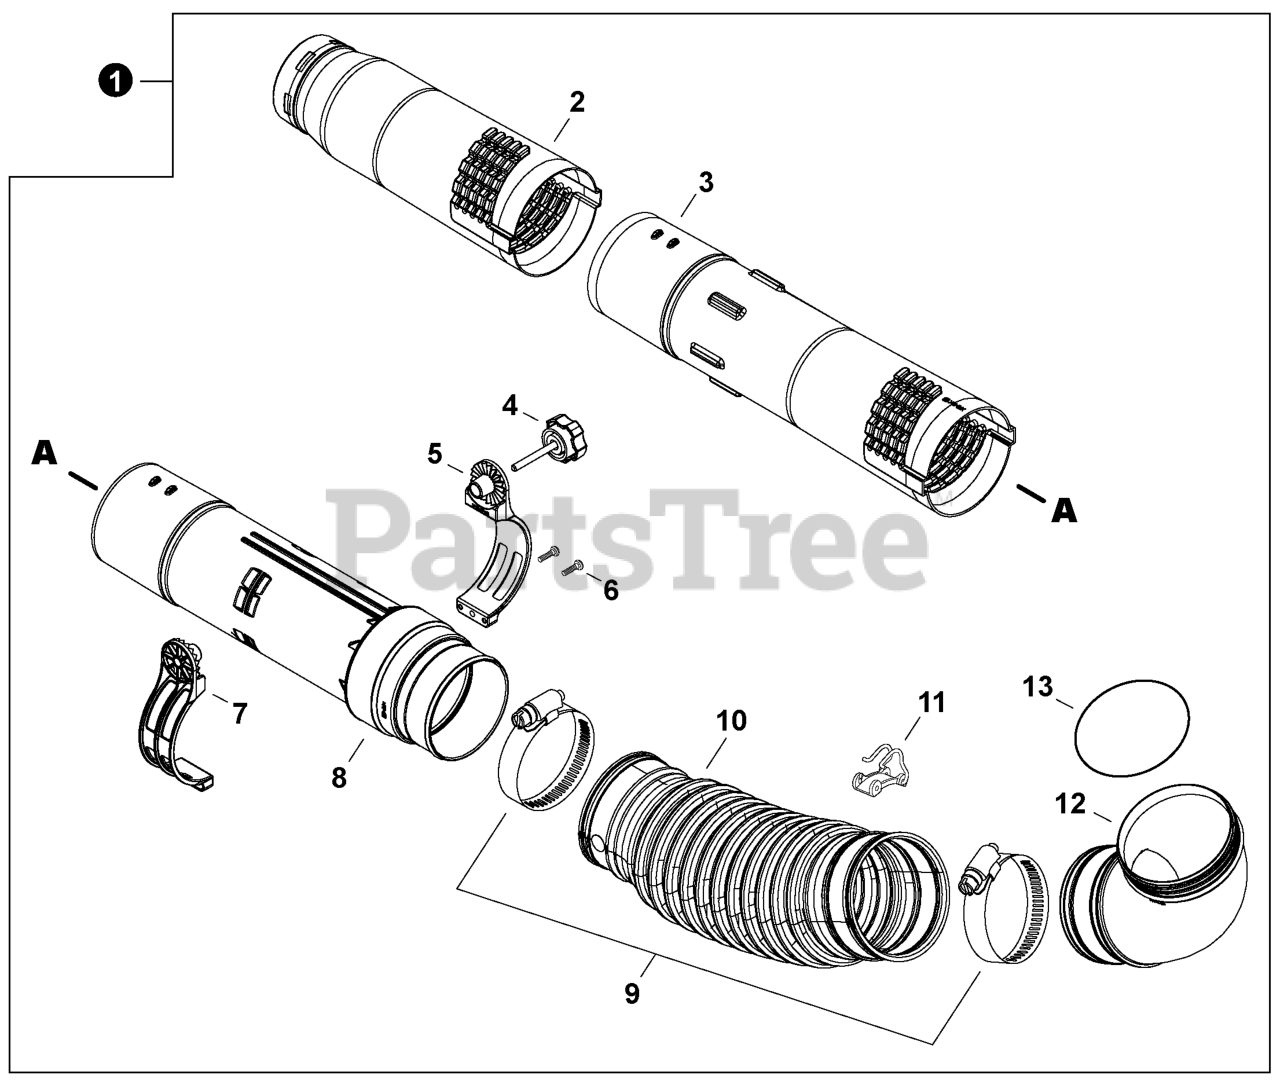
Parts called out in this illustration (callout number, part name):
1	TUBE KIT, BLOWER, TUBE MOUNT
2	TUBE, BLOWER - NOZZLE
3	TUBE, BLOWER - STRAIGHT
4	KNOB, SCREW
5	BRACKET, HANDLE - RIGHT
6	BOLT, TORX 5x20
7	BRACKET, HANDLE - LEFT
8	TUBE, BLOWER - SWIVEL
9	TUBE, BLOWER - FLEXIBLE
10	CLAMP - BAND
11	CLIP, CABLE
12	TUBE, BLOWER - ELBOW
